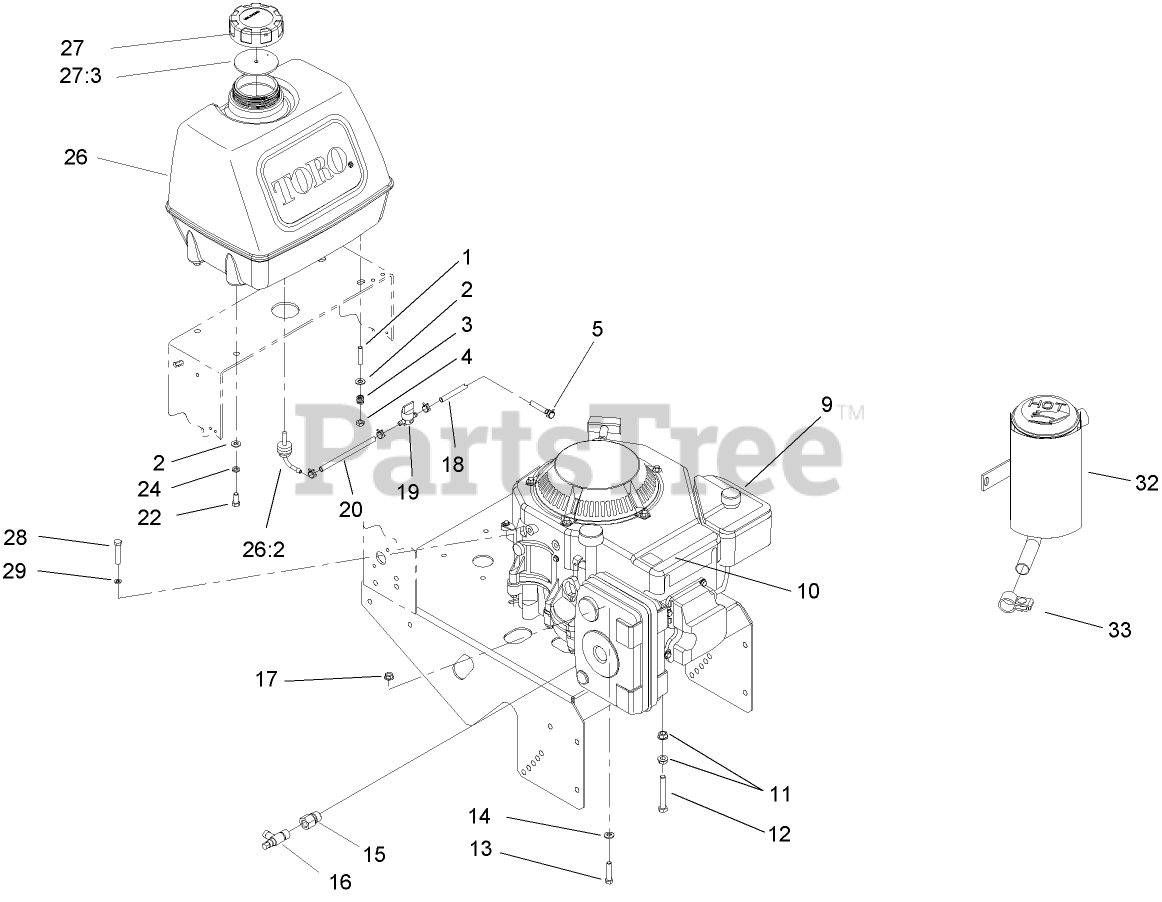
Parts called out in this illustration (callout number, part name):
2	WASHER-PLAIN
3	SPRING-TANK, FUEL
4	NUT-LOCK, NI
10	DECAL-SURFACE, HOT
11	NUT-HHF, WHIZ
12	SCREW-HH
13	SCREW-HH
14	WASHER-SPRING
15	Adapter
16	Valve-Drain, Oil
17	NUT-HF
18	HOSE-FUEL
19	VALVE-FUEL
20	HOSE-FUEL
22	SCREW-HH
24	WASHER-LOCK
26	FUEL TANK ASM
26:2	FITTING-FUEL, BULKHEAD
27	GAS CAP ASM
27:3	GASKET-CAP, GAS
28	SCREW-HH
29	WASHER-LOCK
32	MUFFLER
33	CLAMP-MUFFLER
